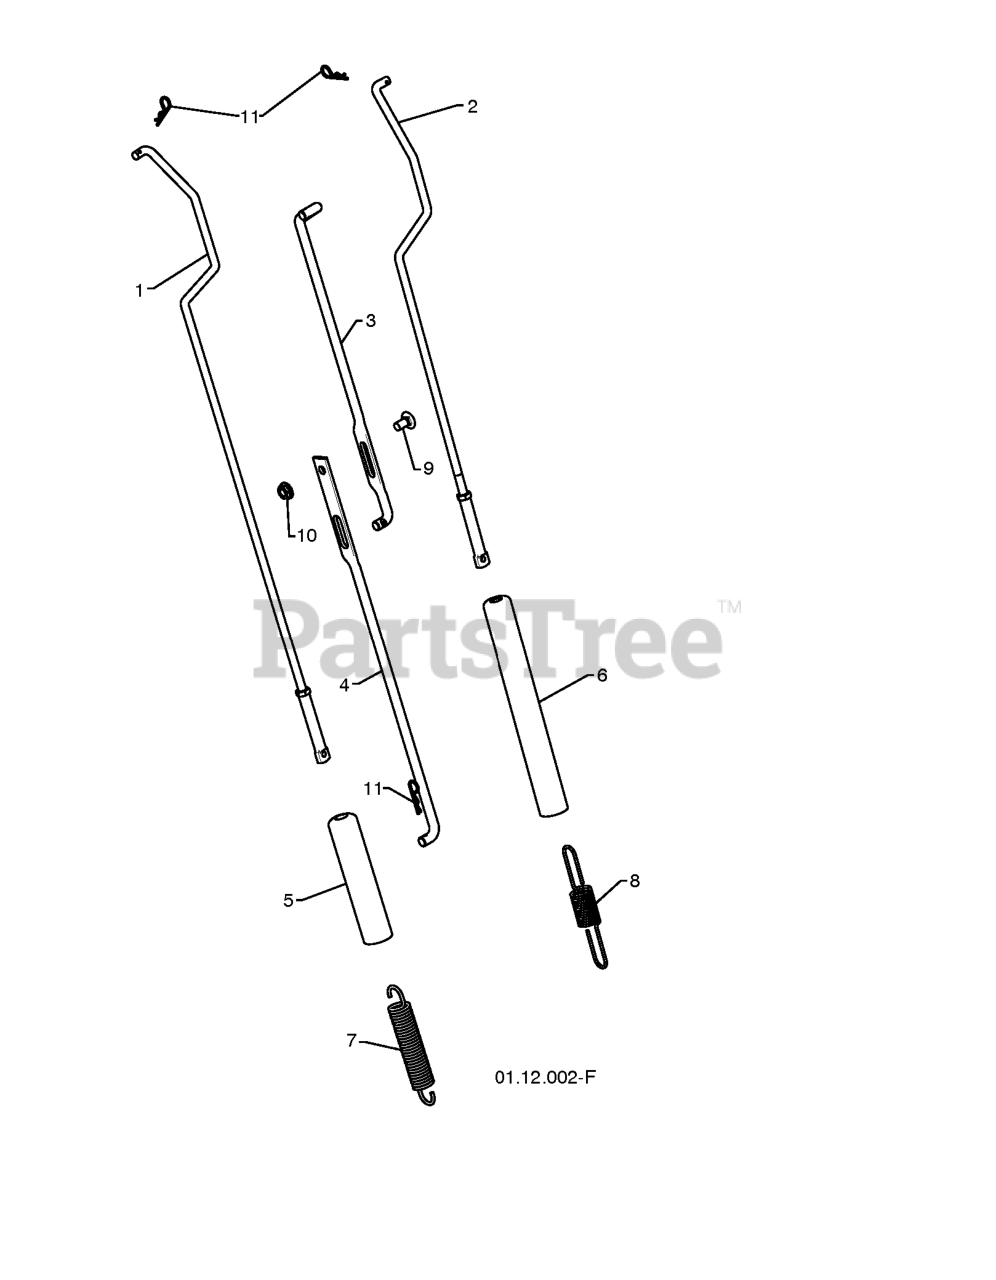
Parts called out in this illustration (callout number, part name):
1	ROD.CONTROL.IMPELLER.HYDRO
2	TRACTION ROD ASSY.
3	ROD.SHIFTER.TOP.HYD.SNOW
4	ROD, LOWER, SPEED CONTROL
5	SLEEVE, SPRING
6	SLEEVE, SPRING
7	SPRING, AUGER CONTROL
8	SPRING, TRACTION DRIVE
9	BOLT
10	NUT.FLANGE.5/16
11	SPRING RETAINER
